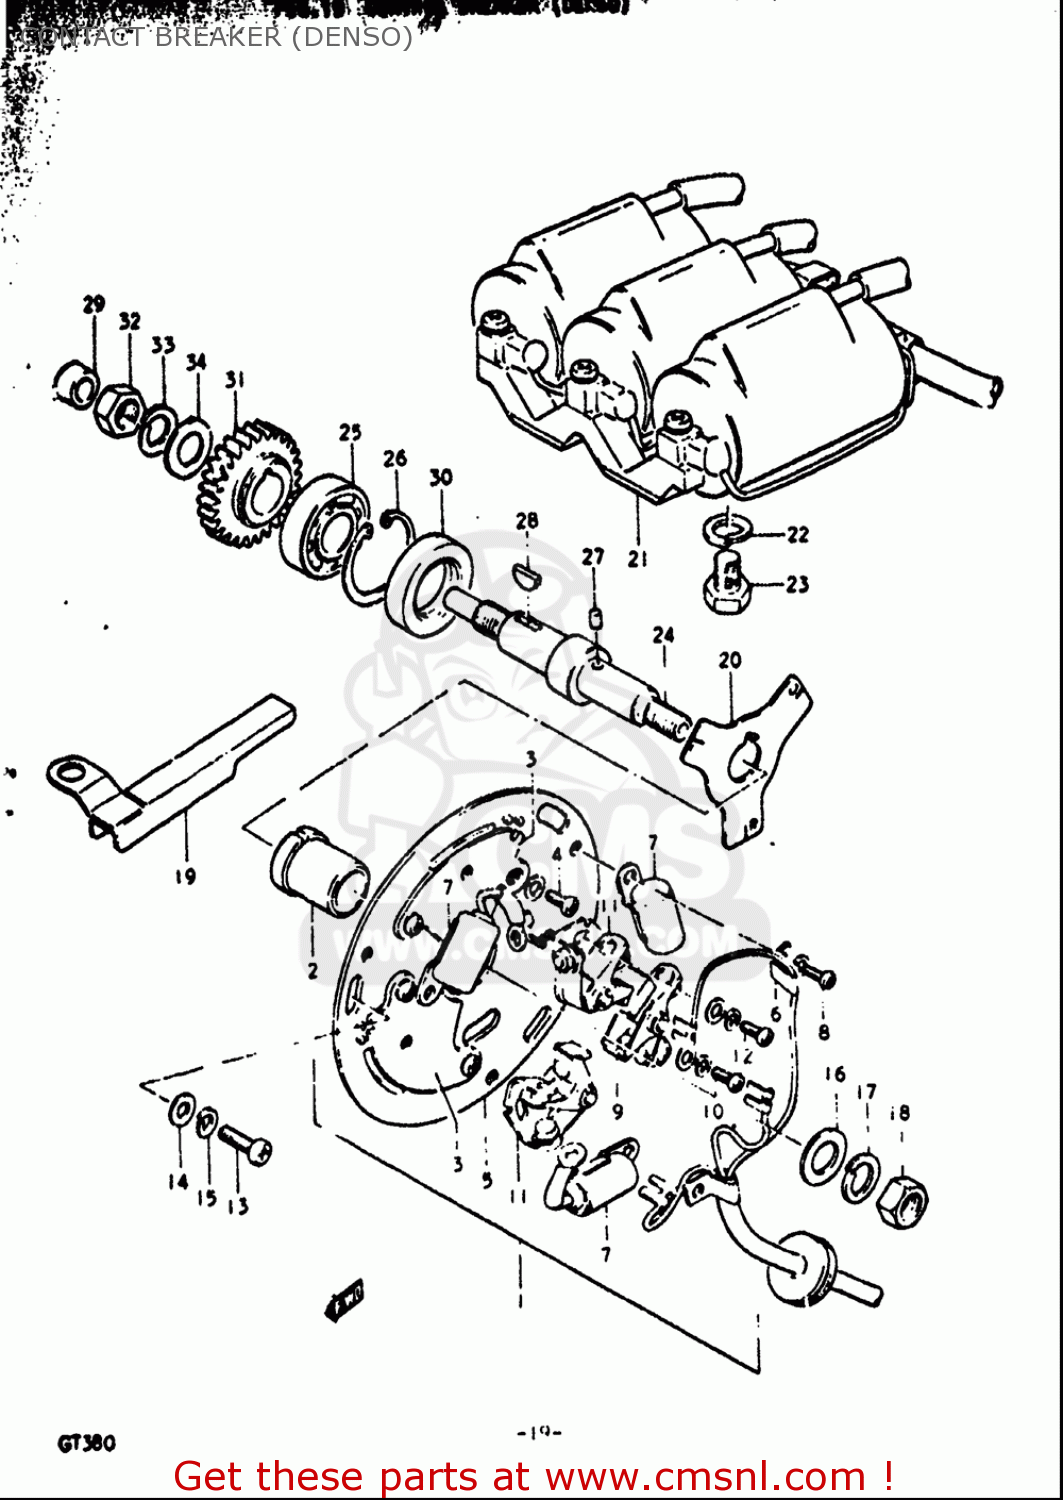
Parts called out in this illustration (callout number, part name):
3	SHIFT PLATE, CONTACT POINT
4	SCREW 4X6
7	CONDENSER
8	SCREW
9	POINT ASSY
10	SCREW 4X6
11	POINT ASSY
12	SCREW 4X6
13	SCREW(5X12)
14	WASHER
15	WASHER,LOCK
16	WASHER
17	WASHER,LOCK
18	NUT
22	WASHER,LOCK
23	BOLT
25	BEARING
26	CIRCLIP
27	PIN
28	KEY
30	SEAL,OIL(20X35X7)
31	GEAR,BREAKER CAMSHAFT DRIVEN
32	NUT
33	WASHER,LOCK
34	WASHER
